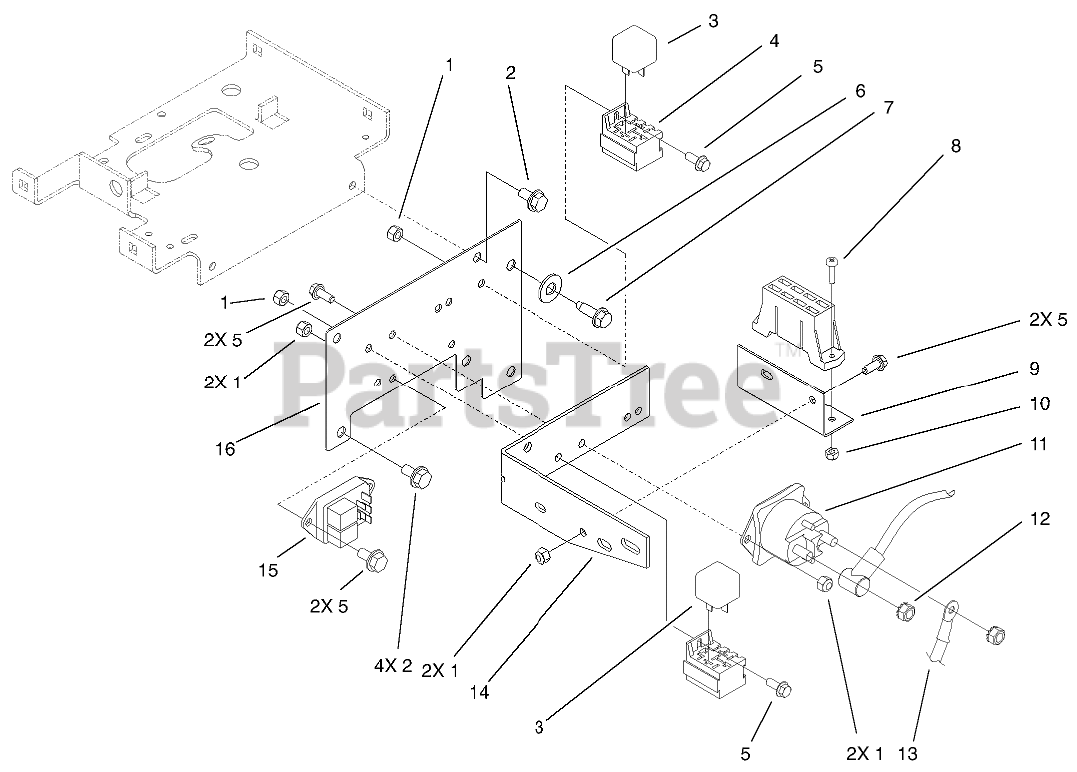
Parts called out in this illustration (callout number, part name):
1	NUT-LOCK, NI
2	SCREW-HWHTF
3	RELAY
4	HARNESS-WIRE
5	SCREW-HHF
6	WASHER-FLAT
7	SCREW-HWHTF
8	SCREW-PAN
9	FUSE HOLDER
10	NUT-LOCK, NI
11	SOLENOID
12	NUT-KEPS
13	CABLE-BATTERY, POSITIVE
14	BRACKET-BELT
15	MODULE-CLUTCH
16	PLATE-HOODSTAND, FRONT
